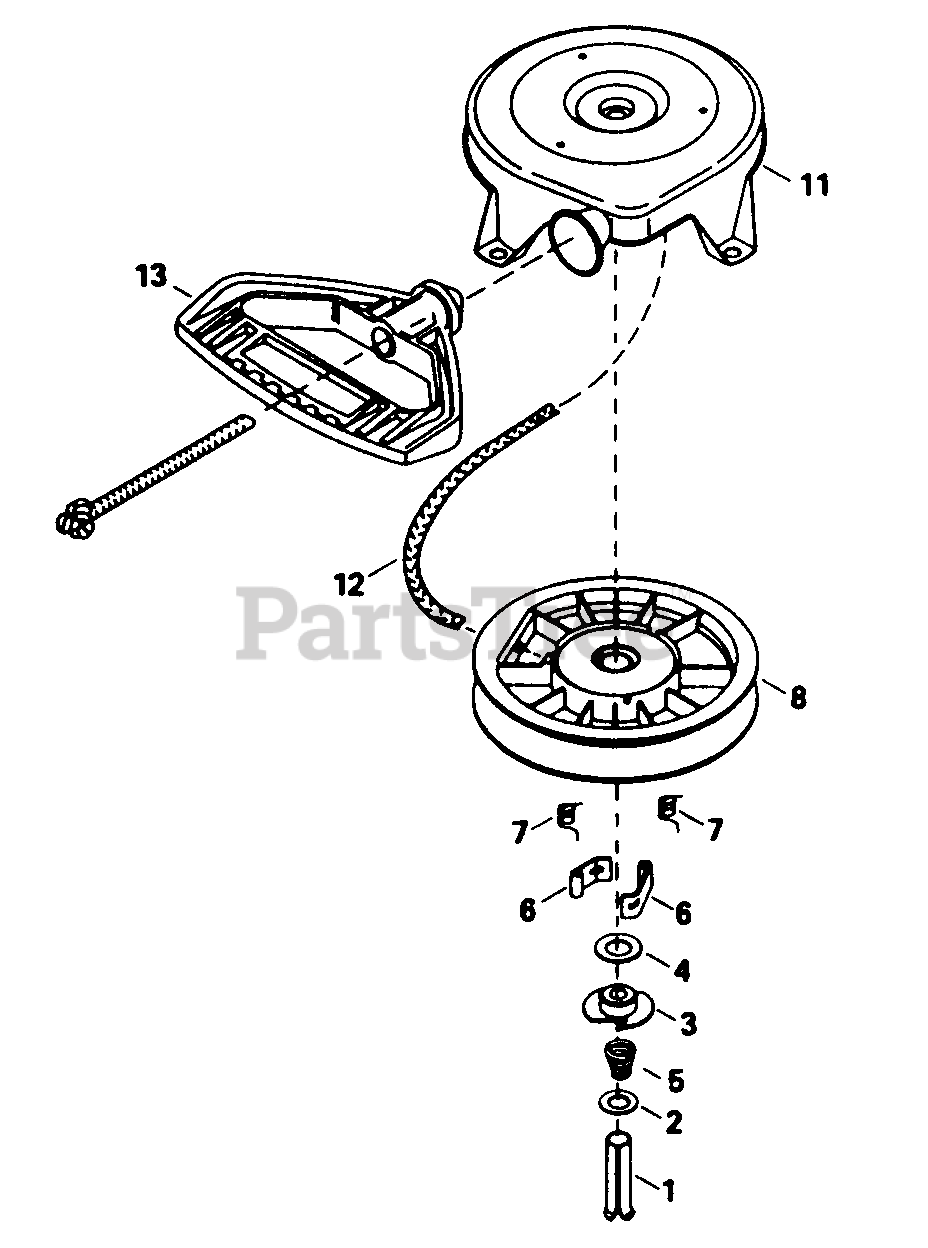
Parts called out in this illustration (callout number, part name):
1	Pin, Spring
5	Spring, Brake
6	Dog, Starter
7	Spring, Dog
8	Pulley & Rewind Spring Ass'y.
11	Housing Ass'y., Starter
12	Rope, Starter (Length 114" & 11/64" Dia.)
13	Handle, Mitten Grip
